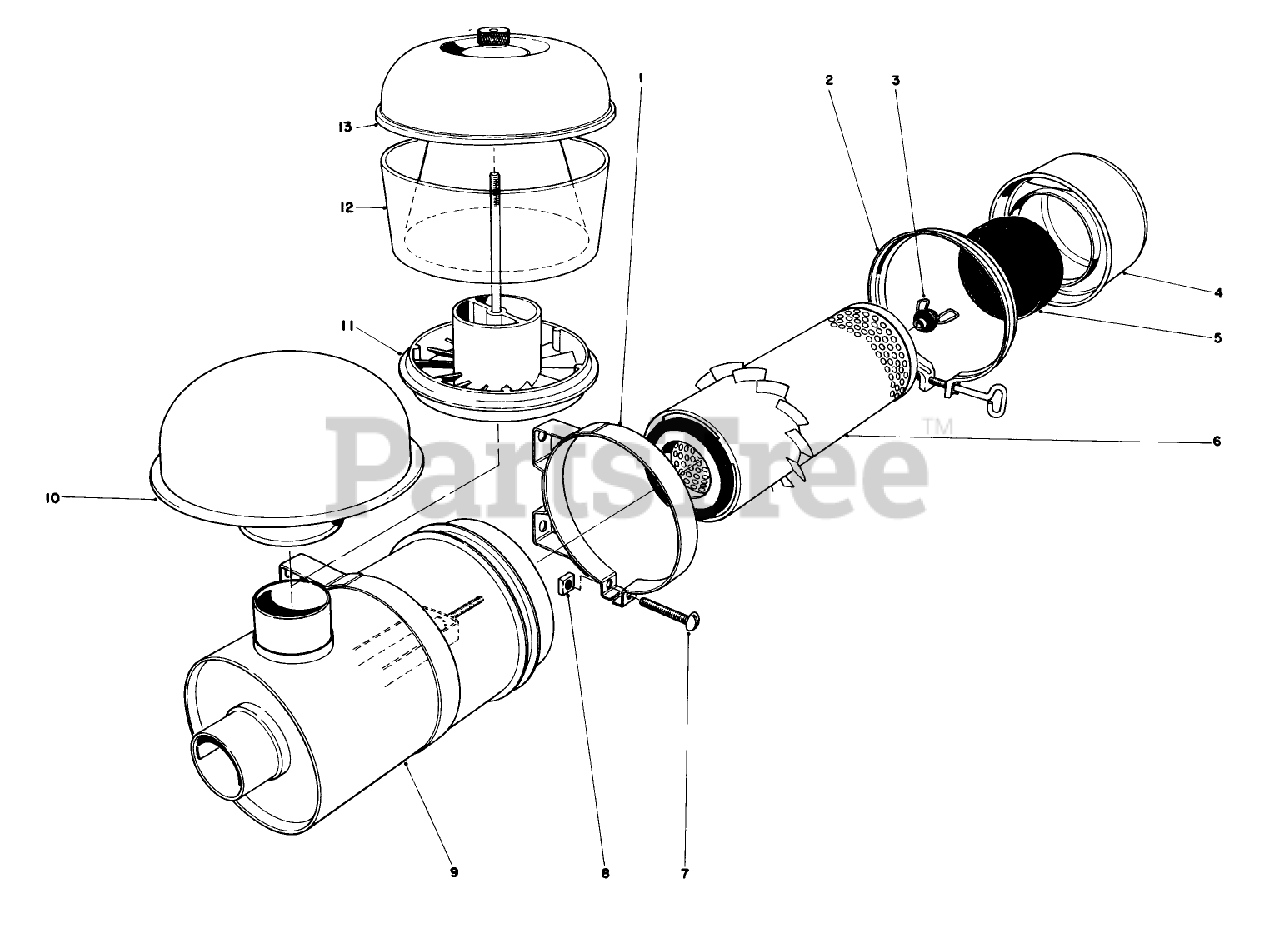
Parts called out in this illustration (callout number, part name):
1	MTG BAND ASM
2	CLAMP ASM
3	NUT ASM
4	CUP ASM
5	BAFFLE
6	ELEMENT ASM
7	SCREW
8	NUT-SQUARE
9	Body Assembly
10	HOOD-INLET, AIR
11	SLEEVE ASM
12	BOWL-CLEAR
13	COVER ASM
